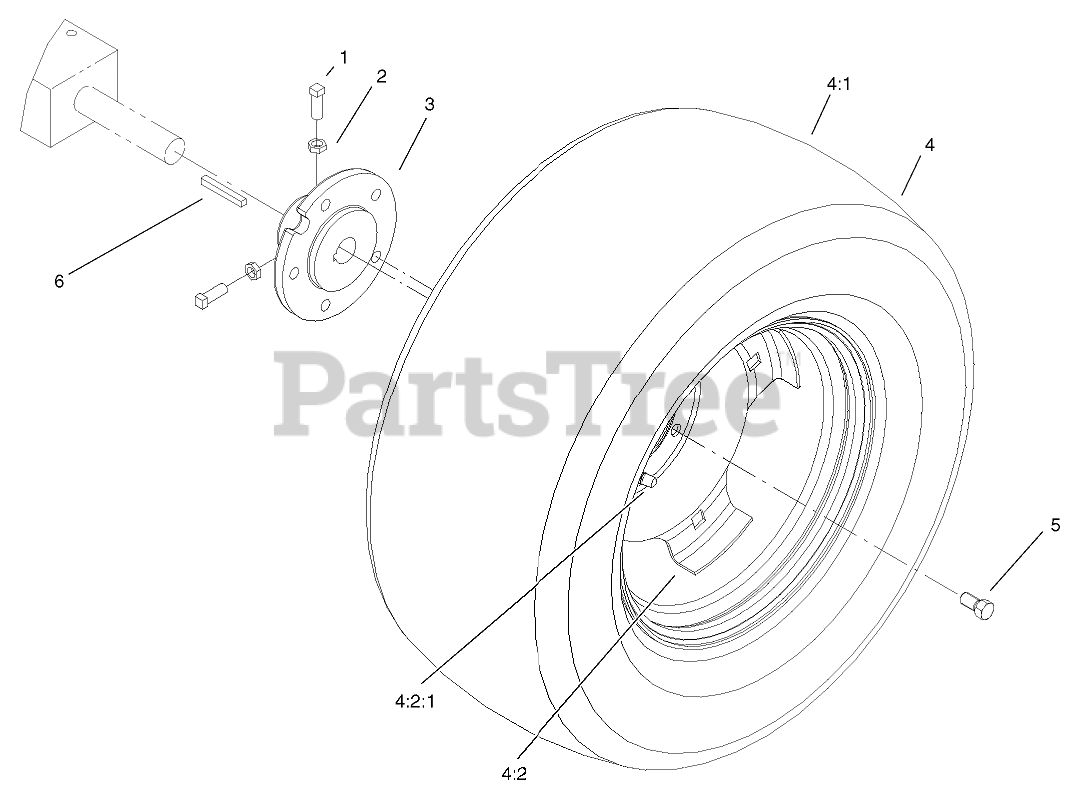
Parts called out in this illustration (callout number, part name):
1	SCREW-SET, SQH
2	NUT-JAM
3	HUB-WHEEL
4	REAR WHEEL & TIRE ASM
4:2	WHEEL
4:2:1	VALVE
5	BOLT-LUG
6	KEY-SQUARE
